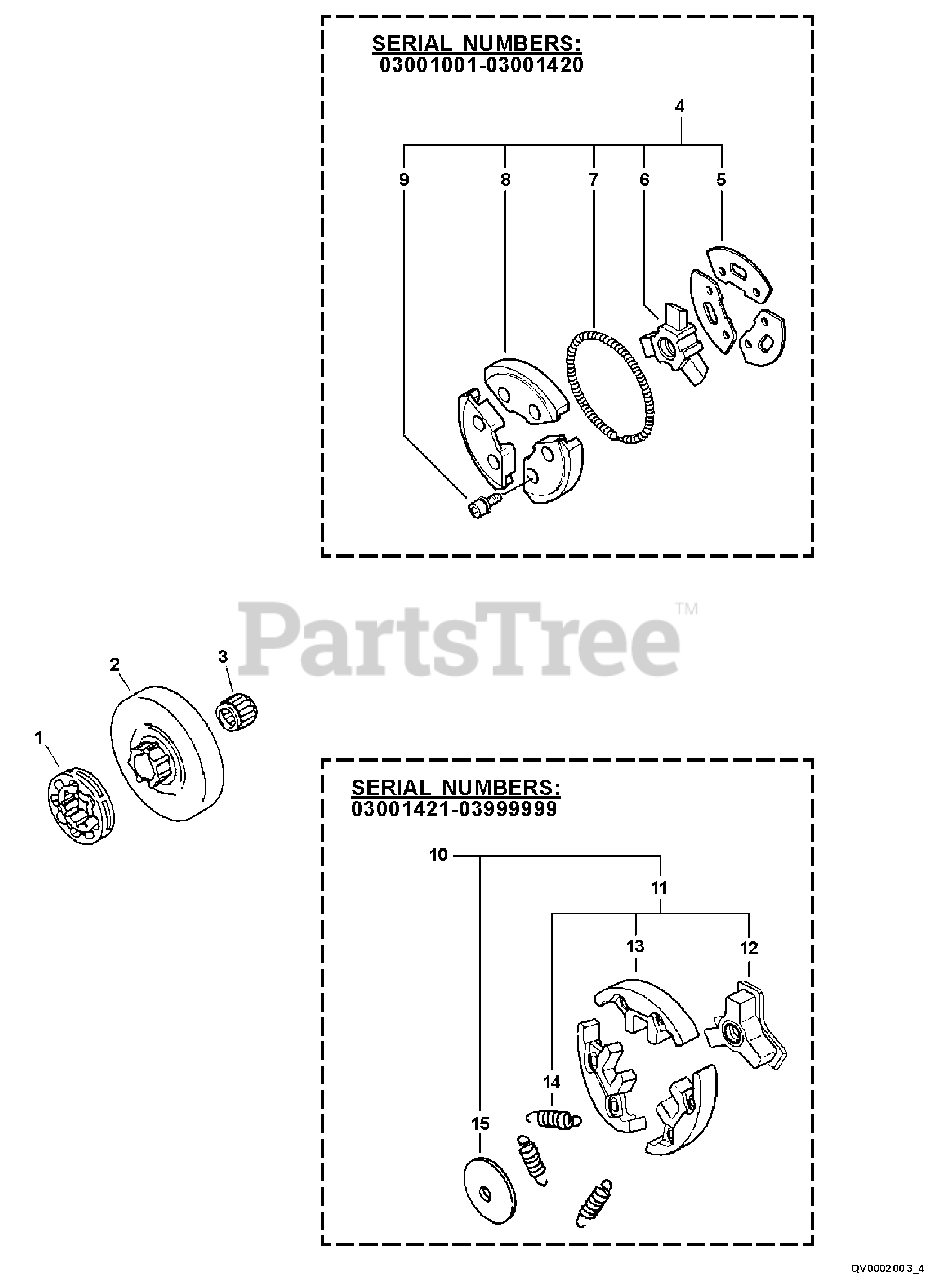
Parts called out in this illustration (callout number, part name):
1	SPROCKET, RIM 3/8"×7T
2	DRUM, CLUTCH
3	BEARING, NEEDLE
4	CLUTCH ASSY
5	PLATE, CLUTCH
6	HUB, CLUTCH
7	SPRING, TENSION
8	CLUTCH SHOE SET
9	BOLT 4×6
10	CLUTCH ASSY
11	CLUTCH ASSY
12	HUB, CLUTCH
13	SHOE SET, CLUTCH (3PCS)
14	SPRING, TENSION
15	PLATE, CLUTCH
